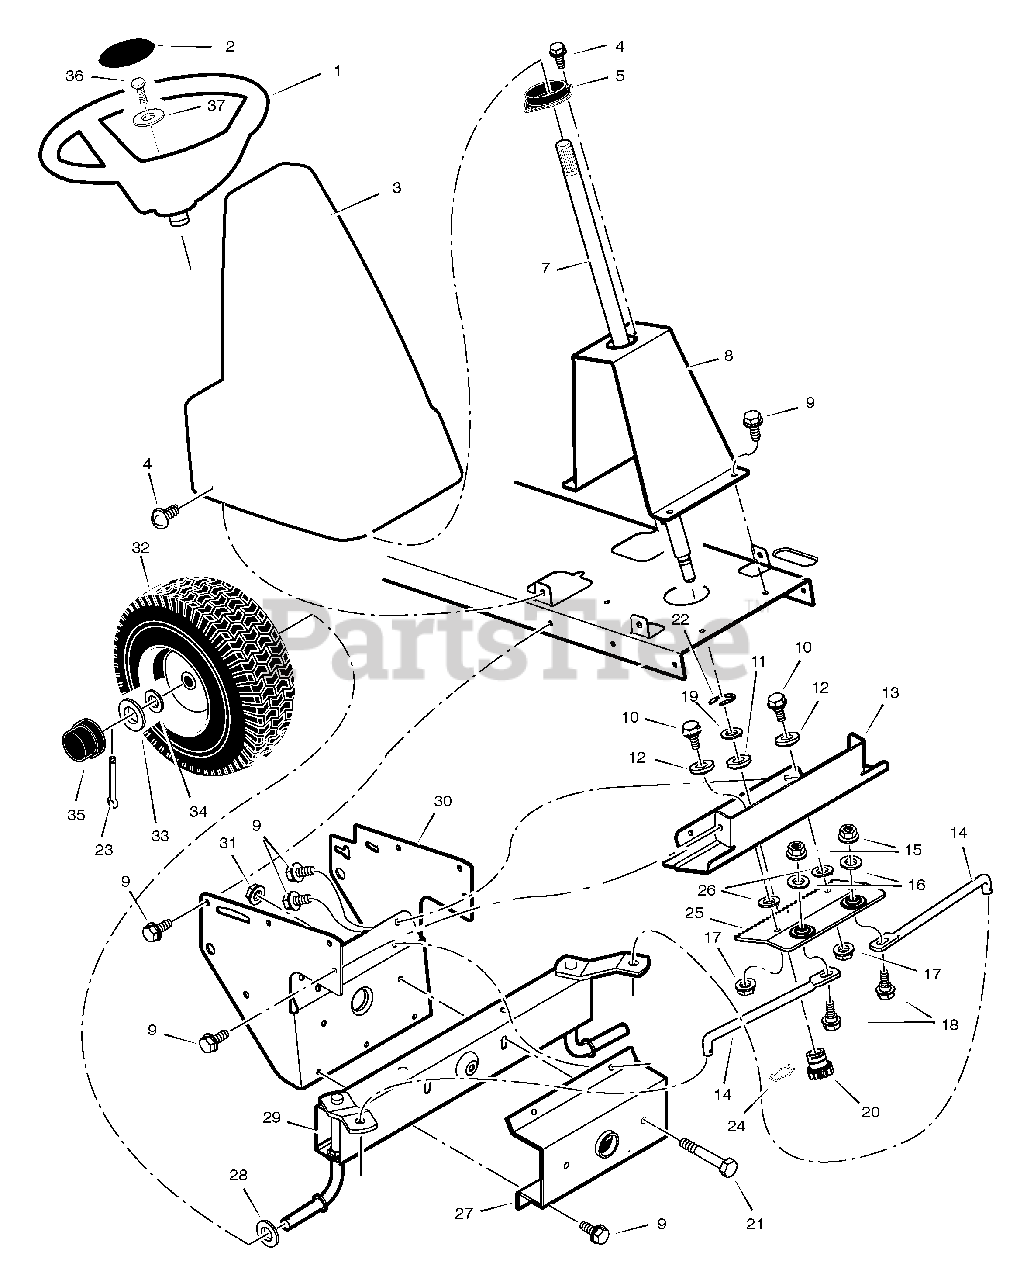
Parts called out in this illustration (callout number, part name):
1	WHEEL, Steering
2	Cap, Steering
3	Console, High -Black
5	BEARING, Upper Steering
7	Shaft, Steering
8	SUPPORT, Steering
10	BOLT, Shoulder
11	BEARING, Lower Steering
13	Plate, Gear Mounting
15	NUT, Flange
17	NUT, Flange
18	BOLT, Hex
19	WASHER, 1-1.3 16G FLT
20	Gear, Pinion
21	BOLT, Hex
22	E-Ring, Retainer
23	PIN, Cotter
24	Retainer, Spring
25	Rack, Steering
27	BRACKET, Axle Front
29	Axle & Spindle Assembly
30	BRACKET, Support
31	NUT, Flange
32	WHEEL, Front
35	Cap, Hub
